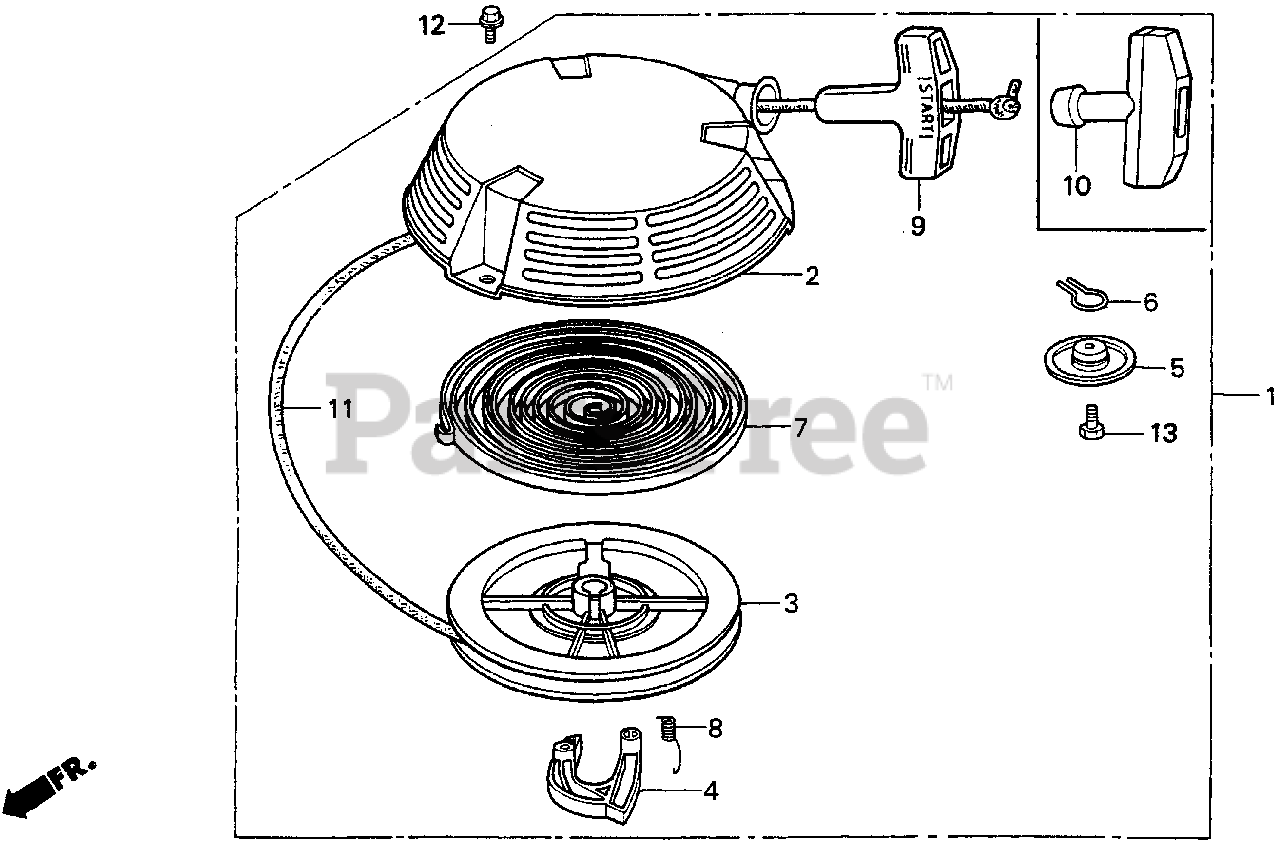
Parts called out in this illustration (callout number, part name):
1	STARTER ASSY., RECOIL *R8* (BRIGHT RED)
1	STARTER ASSY., RECOIL *R280* (POWER RED)
2	CASE, RECOIL STARTER *R280* (POWER RED)
3	PULLEY, RECOIL STARTER
4	RATCHET, STARTER
5	PLATE, FRICTION
6	SPRING, FRICTION
7	SPRING, RECOIL STARTER
8	SPRING, RETURN
9	KNOB, RECOIL STARTER
10	GRIP, STARTER
11	ROPE, RECOIL STARTER
11	ROPE, LONG (55")
12	BOLT, FLANGE (6X8)
13	BOLT, HEX. (6X12)
